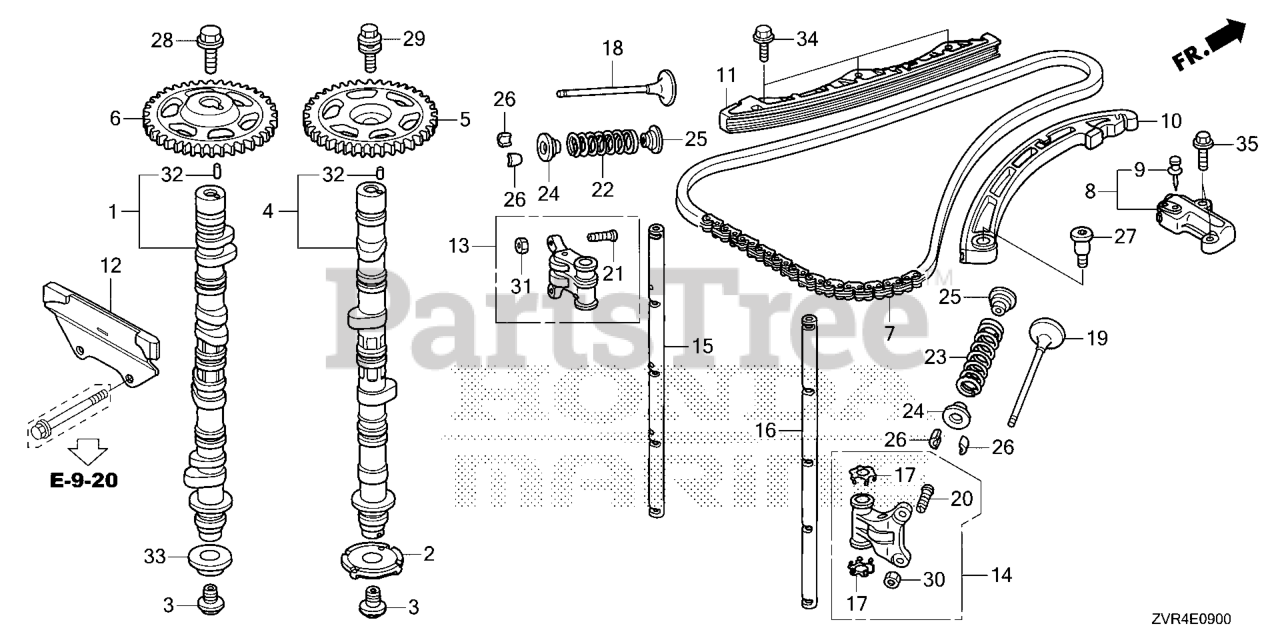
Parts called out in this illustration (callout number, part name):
1	CAMSHAFT, IN.
2	PLATE, TDC PULSE
3	BOLT, SEALING (14MM)
4	CAMSHAFT, EX.
5	SPROCKET, CAM CHAIN DRIVEN (46T)
6	SPROCKET, CAM CHAIN DRIVEN IN. (46T)
7	CHAIN (176L) (DAIDO)
8	TENSIONER ASSY., CAM CHAIN
9	STOPPER (TOOL)
10	ARM, CAM CHAIN TENSIONER
11	GUIDE, CAM CHAIN
12	GUIDE B, CAM CHAIN
13	ARM ASSY., ROCKER
14	ARM ASSY., EX. ROCKER
15	SHAFT, IN. ROCKER
16	SHAFT, EX. ROCKER
17	WASHER, THRUST
18	VALVE, IN.
19	VALVE, EX.
20	SCREW, TAPPET ADJUSTING
21	SCREW, TAPPET ADJUSTING
22	SPRING, IN. VALVE (PINK) (NIPPON HATSUJO)
23	SPRING, EX. VALVE (GRAY) (NIPPON HATSUJO)
24	RETAINER, VALVE SPRING
25	SEAT, VALVE SPRING
26	COTTER, VALVE (FUJI VALVE)
27	BOLT, TENSIONER PIVOT
28	BOLT, FLANGE (12X47)
29	BOLT, FLANGE (10X32)
30	NUT, TAPPET ADJUSTING (TOKAI TRW)
31	NUT, TAPPET ADJUSTING
32	PIN, DOWEL (4.2X10.3)
33	COLLAR, CAMSHAFT
34	BOLT, FLANGE (6X20)
35	BOLT, FLANGE (6X30)
